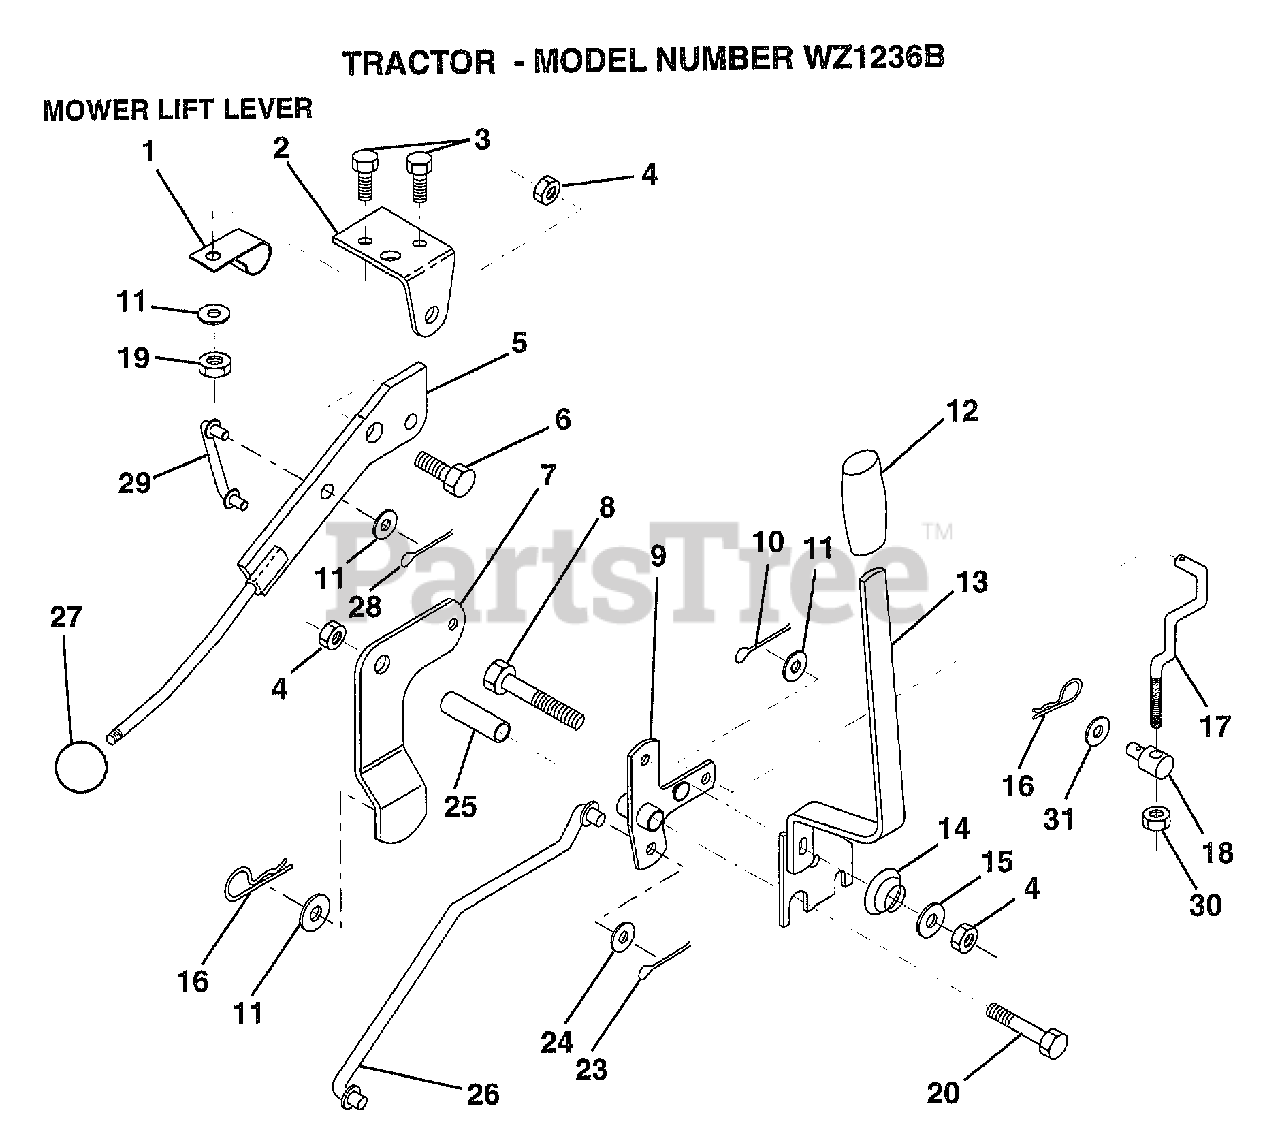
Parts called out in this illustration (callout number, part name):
1	"CLIP,INSULATOR"
2	BRKT CLUTCH
3	BOLT HXHD FIN
5	LEVER.ASM.CLUTCH
6	"BOLT, SHOULDER LT"
7	MWR CLUTCH ARM AS
8	BOLT
9	"BELLCRANK,LIFT"
10	COTTER PIN
11	WASHER
13	HANDLE.ASM.LIFT
14	SPRING COMPRESSIO
15	WASHER T
16	SPRING.RETAINER
17	"LINK,LIFT FRT"
18	TRUNION ADJ
20	BOLT
23	PIN COTTER 1/8
25	TUBE SPACER
26	ROD LIFT MOWER
27	KNOB T(3/8 HOLE)
29	CLUTCH LINK
30	NUT
31	WASHER
